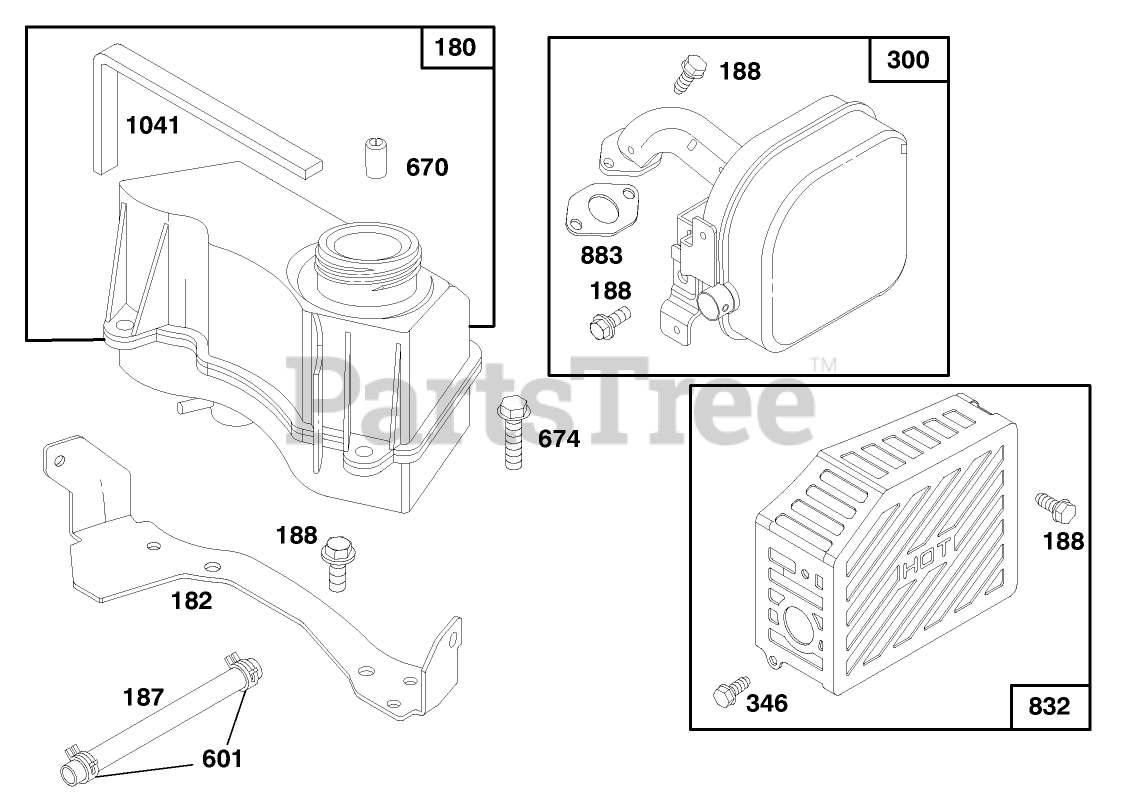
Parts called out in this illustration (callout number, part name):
180	TANK ASSY - FUEL
300	MUFFLER - EXHAUST
670	SPACER
674	SCREW - HEX HEAD
